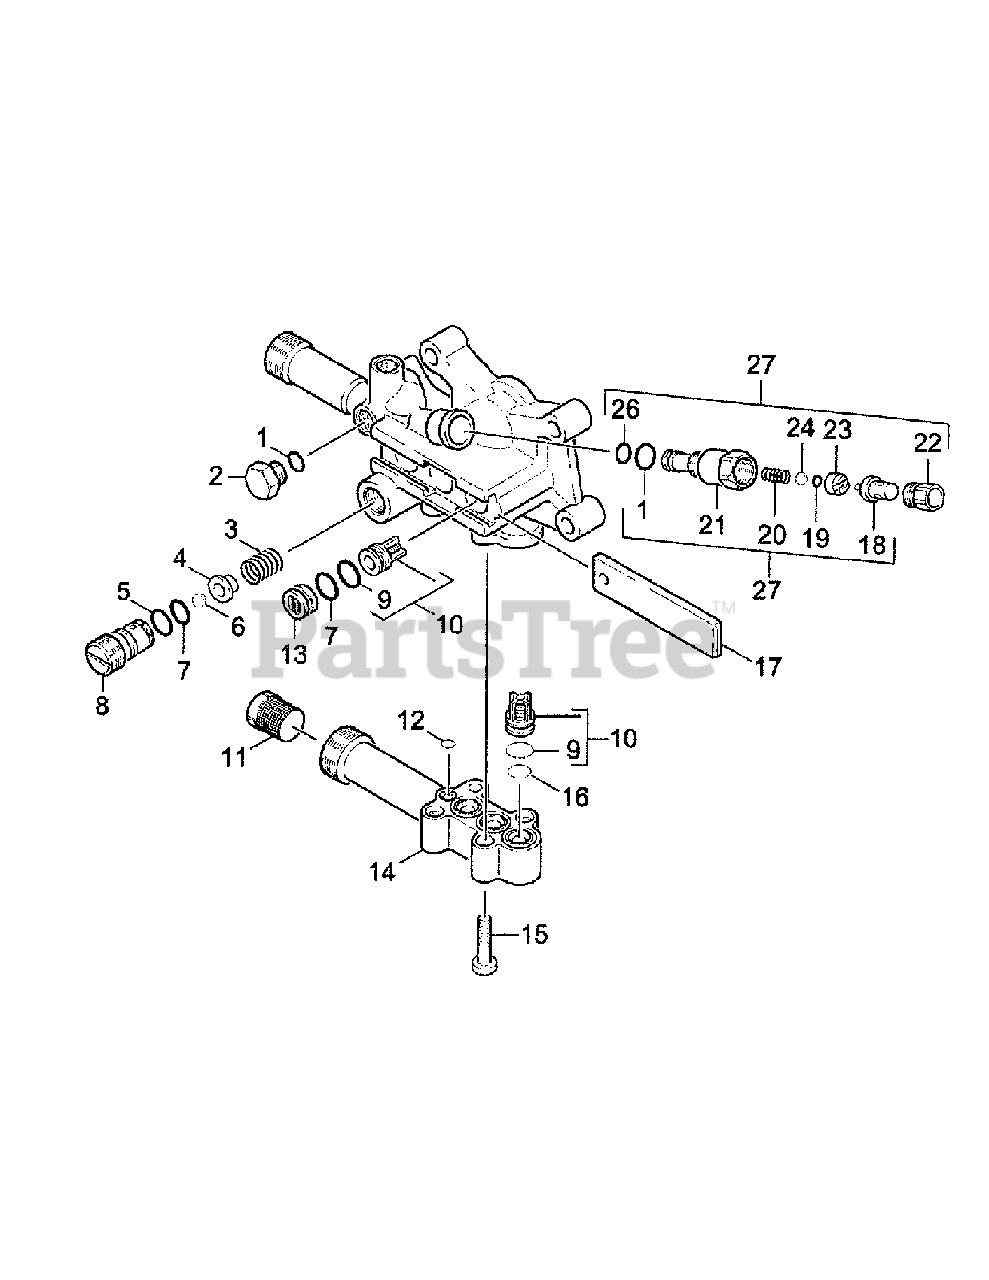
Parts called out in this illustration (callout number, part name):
1	Gasket
2	Closing Screw
3	Helical Spring
4	Valve Disc
5	Gasket
6	Ball
7	Gasket
8	Valve Screw
9	Gasket
10	Valve
11	Strainer
12	Gasket
13	Drain Plug
14	Cover
15	Screw
16	Gasket
17	Plate
18	Valve
19	Gasket
20	Helical Spring
21	Union Screw
22	Closing Screw
23	Washer
24	Ball
26	Gasket
27	Valve
